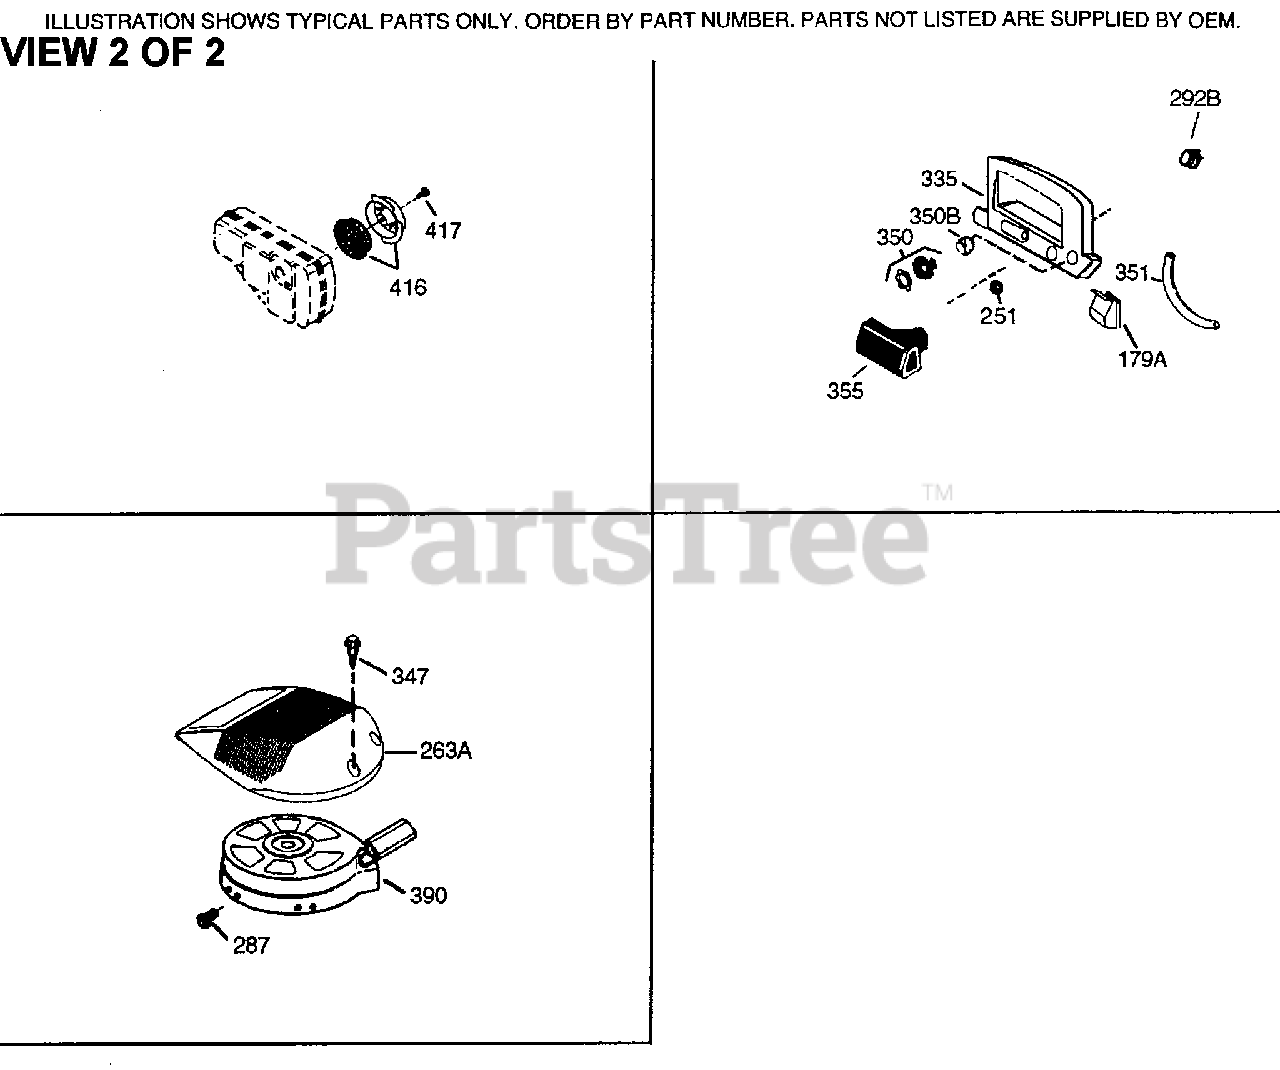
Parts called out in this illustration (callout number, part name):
251	Lock Nut 1/4-20
263A	Starter Grill
287	Screw, 8-32 x 21/64"
347	Screw, 10-32 x 27/64"
350	Primer
370A	Lubrication Decal
390	Rewind Starter NOTE: This engine cou ld hav e been built with 590739 start er. Refer to the design of the rope p ulley strength ribs for part identifi cation. Individual starter parts do not interchange.
416	Spark Arrestor Kit (Incl. 417) Option al
417	Screw, 8-32 x 3/8" (Optional)
999	Summer Maintenance Kit (incl. Oil, Sp ark Plug, Air Cleaner, & Ultra Fresh)
